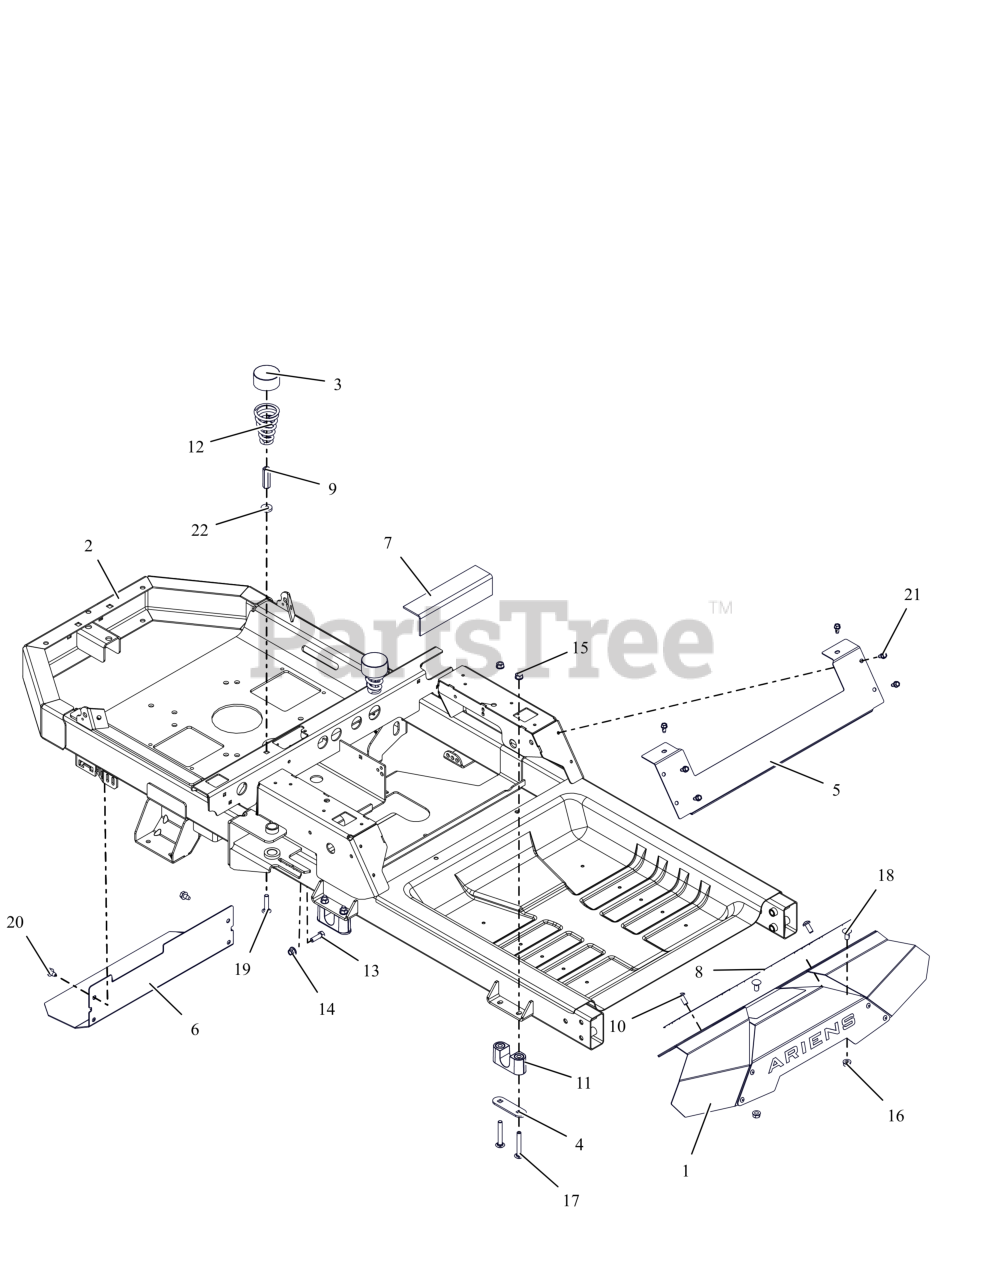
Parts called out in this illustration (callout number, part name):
1	KIT, IKON FOOT REST W/DECAL
2	WLDMT, FRAME IKON XD/ZTX & XL (ORANGE)
3	HUB CAP
4	PLATE, BEARING SUPPORT
5	PLATE, SEAT KICK
6	HEAT, SHIELD
7	PAD, RUBBER-TANK
8	GRIP TAPE, FOOT PLATE
9	NUT, COUPLING .31-18X1.75 ZCC
10	SCR-RDHDSKTAP .31-18X.75 ZCC
11	BSHG, DECK LIFT PIVOT
12	SPRING, SEAT
13	BLT,HEX .31-18X1.00 G5 ZCC
14	NUT,LK-NYL-FLG .31-18 G5ZC120
15	NUT,LK-CTR-FLG .31-18 GF ZCC
16	NUT-LK-TOP-FLG .312-18 GF ZCC
17	BLT, RHSSN.31-18X2.25 G5 ZCC
18	BLT,RHSN .31-18X.75 G5 ZCC
19	BLT,RHSN .31-18X1.50 G5 ZCC
20	SCR,TAP .312-18X.50 HWH TR ZCC
21	SCR-TAP .25-20X.50 HWH ZCC
22	WSHR, FLT .328X.870X.179 ZCC
